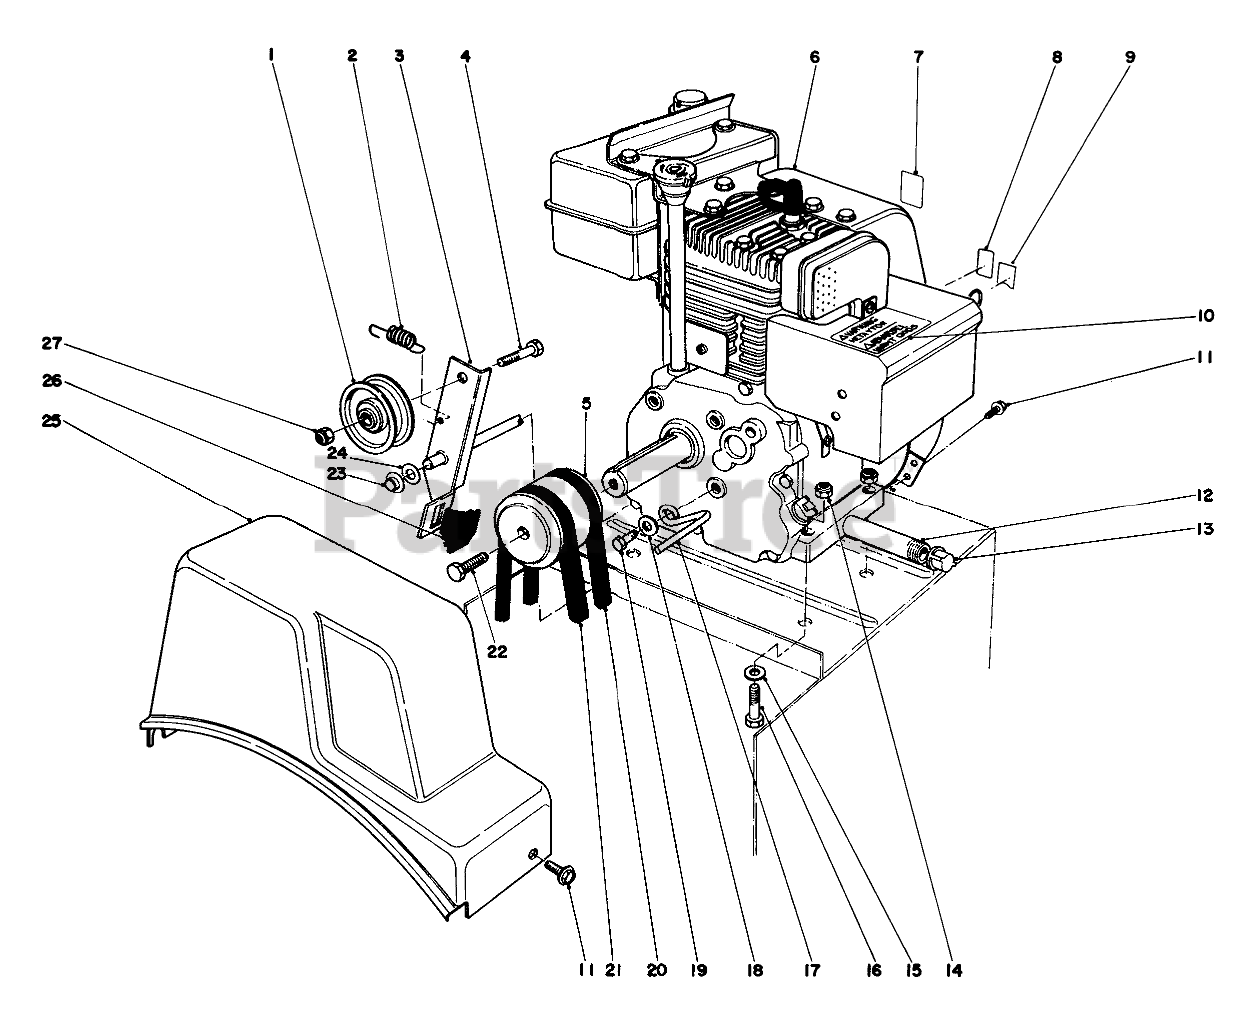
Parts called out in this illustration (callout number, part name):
1	Idler Pulley
2	EXTENSION SPRING
3	Auguer Clutch (Incl. Ref. #26)
4	SCREW-HH
5	Engine Pulley
6	Engine
7	PRIMER DECAL
8	DECAL THROTTLE
9	CHOKE DECAL
10	Decal Hot Surface Warning
11	SCREW
12	PIPE NIPPLE
13	CAP-PIPE
14	NUT-LOCK, NI
15	WASHER-PLAIN
16	SCREW-HH
17	RETAINER-BELT
18	WASHER-LOCK
19	SCREW-HH
20	V BELT-3L, TRACTION
21	V-BELT (29.50 INCH)
22	Screw-Special
23	RETAINER-PUSH ON
24	WASHER-FLAT
25	COVER-BELT
26	Brake Pad
27	NUT-LOCK, CONE
